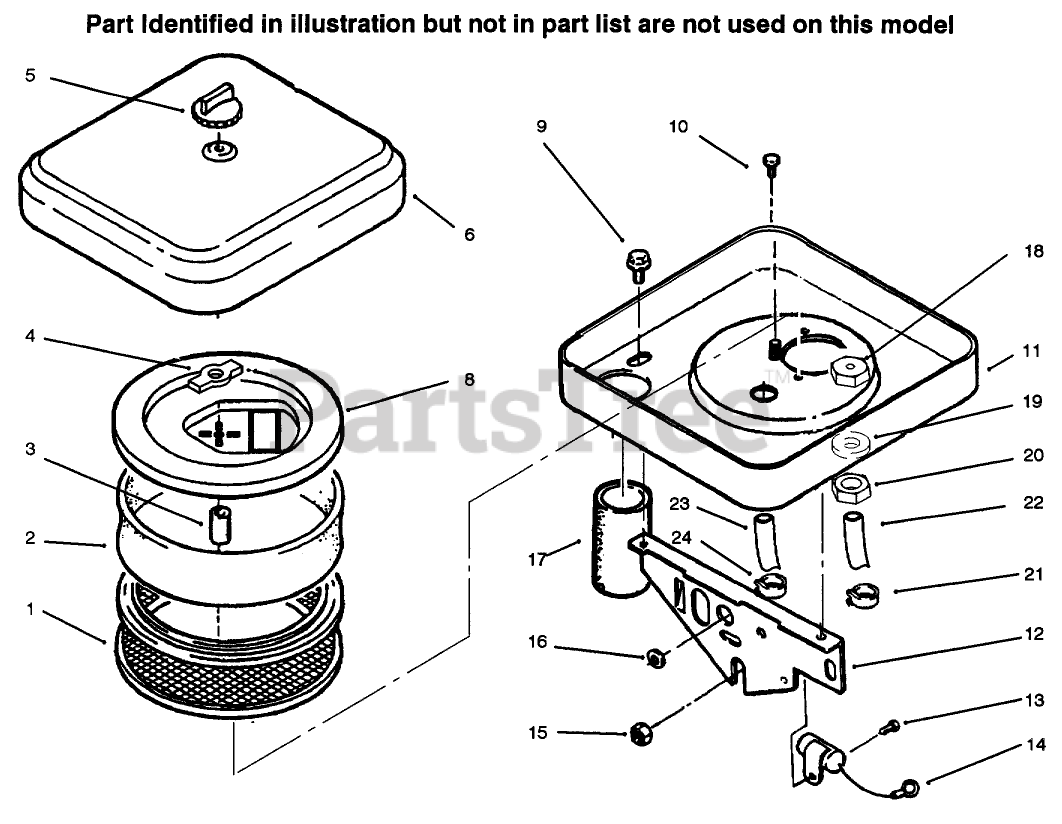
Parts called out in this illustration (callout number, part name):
1	AIR-CLEANER ELEMENT
2	AIR CLEANER ELEMENT
6	COVER - AIR CLEANER
8	ELEMENT COVER KIT
9	SCREW-TAPPING
12	SUPPORT-AIR CLEANER
14	CONDENSER
16	GROMMET
18	FITTING-BARB
